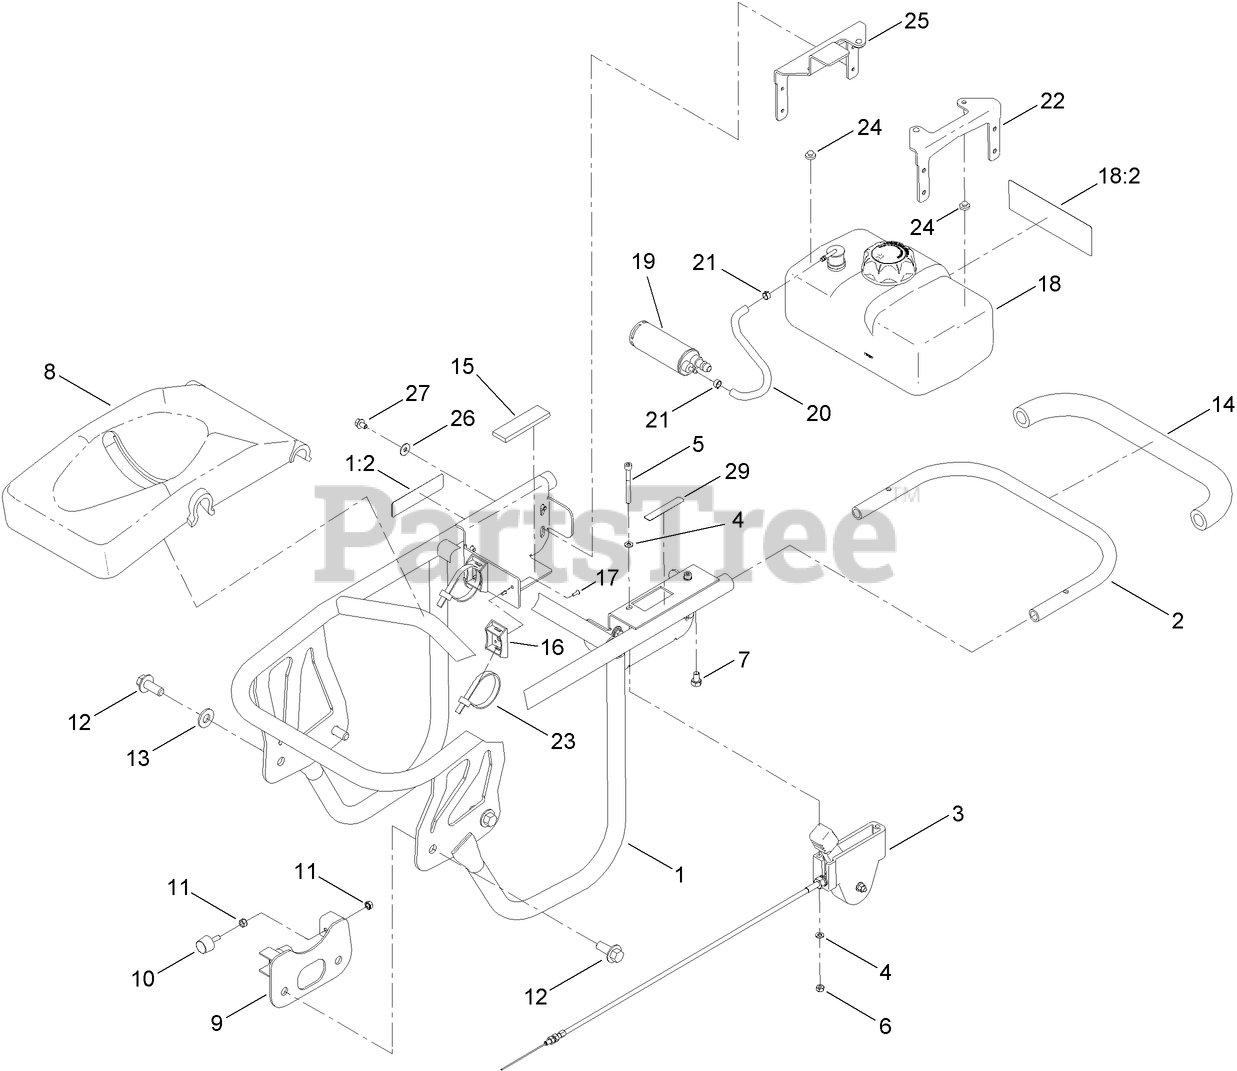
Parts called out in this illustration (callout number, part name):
1	HANDLE ASM
1:2	DECAL-ARRESTER, SPARK
2	HANDLE-RAMMER
3	THROTTLE LEVER ASM
4	WASHER-FLAT
5	SCREW-HSH
6	NUT-LOCK
7	SCREW-HWH
8	COVER-ENGINE
9	STOPPER
10	MOUNT-SHOCK
11	NUT-HEX
12	SCREW-HHF
13	WASHER
14	GRIP-CUSHION, HANDLE
15	PAD-TANK, FUEL
16	BRACKET-CANISTER
17	RIVET
18	1 GALLON FUEL TANK ASM
18:2	DECAL-WARNING
19	CANISTER-CARBON
20	HOSE-FUEL
21	CLAMP-HOSE, FUEL
22	BRACKET-TOP, FUEL TANK
23	TIE-CABLE
24	BUMPER-RUBBER
25	GUARD-TANK, FUEL
26	WASHER-FLAT
27	SCREW-HHF
29	DECAL-THROTTLE
